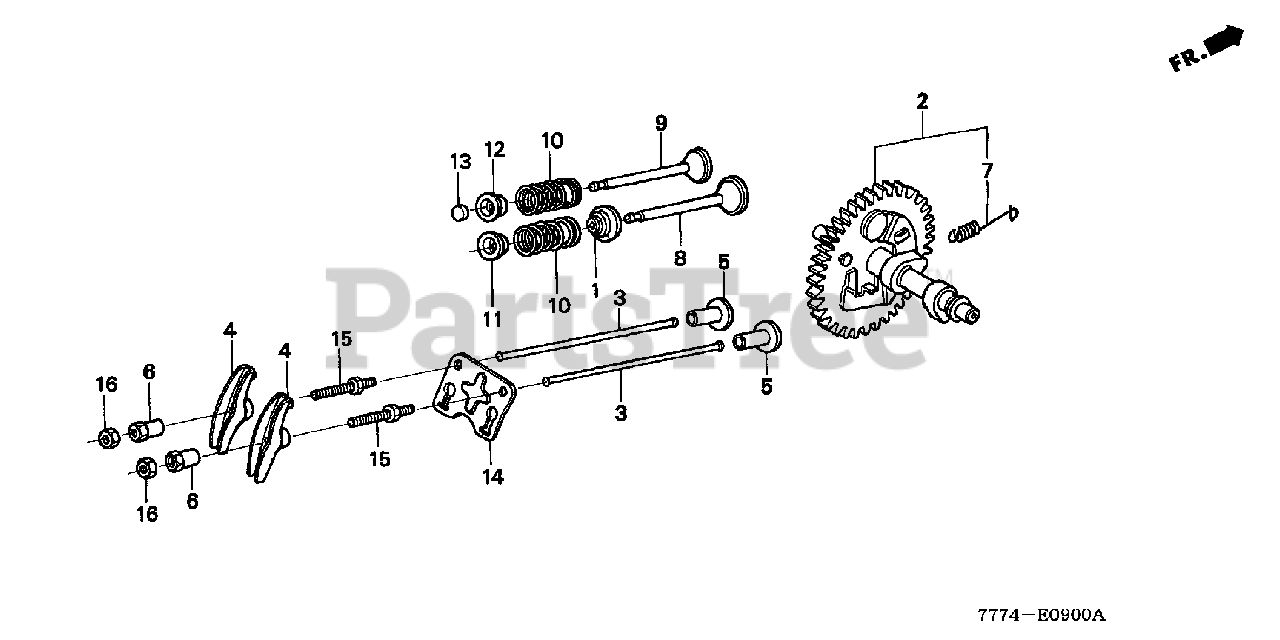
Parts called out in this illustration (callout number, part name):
1	SEAL, VALVE STEM
2	CAMSHAFT ASSY.
3	ROD, PUSH
4	ARM, VALVE ROCKER
5	LIFTER, VALVE
6	PIVOT, ROCKER ARM
7	SPRING, WEIGHT RETURN
8	VALVE, IN.
9	VALVE, EX.
10	SPRING, VALVE
11	RETAINER, IN. VALVE SPRING
12	RETAINER, EX. VALVE SPRING
13	ROTATOR, VALVE
14	PLATE, PUSH ROD GUIDE
15	BOLT, PIVOT (8MM)
16	NUT, PIVOT ADJUSTING
